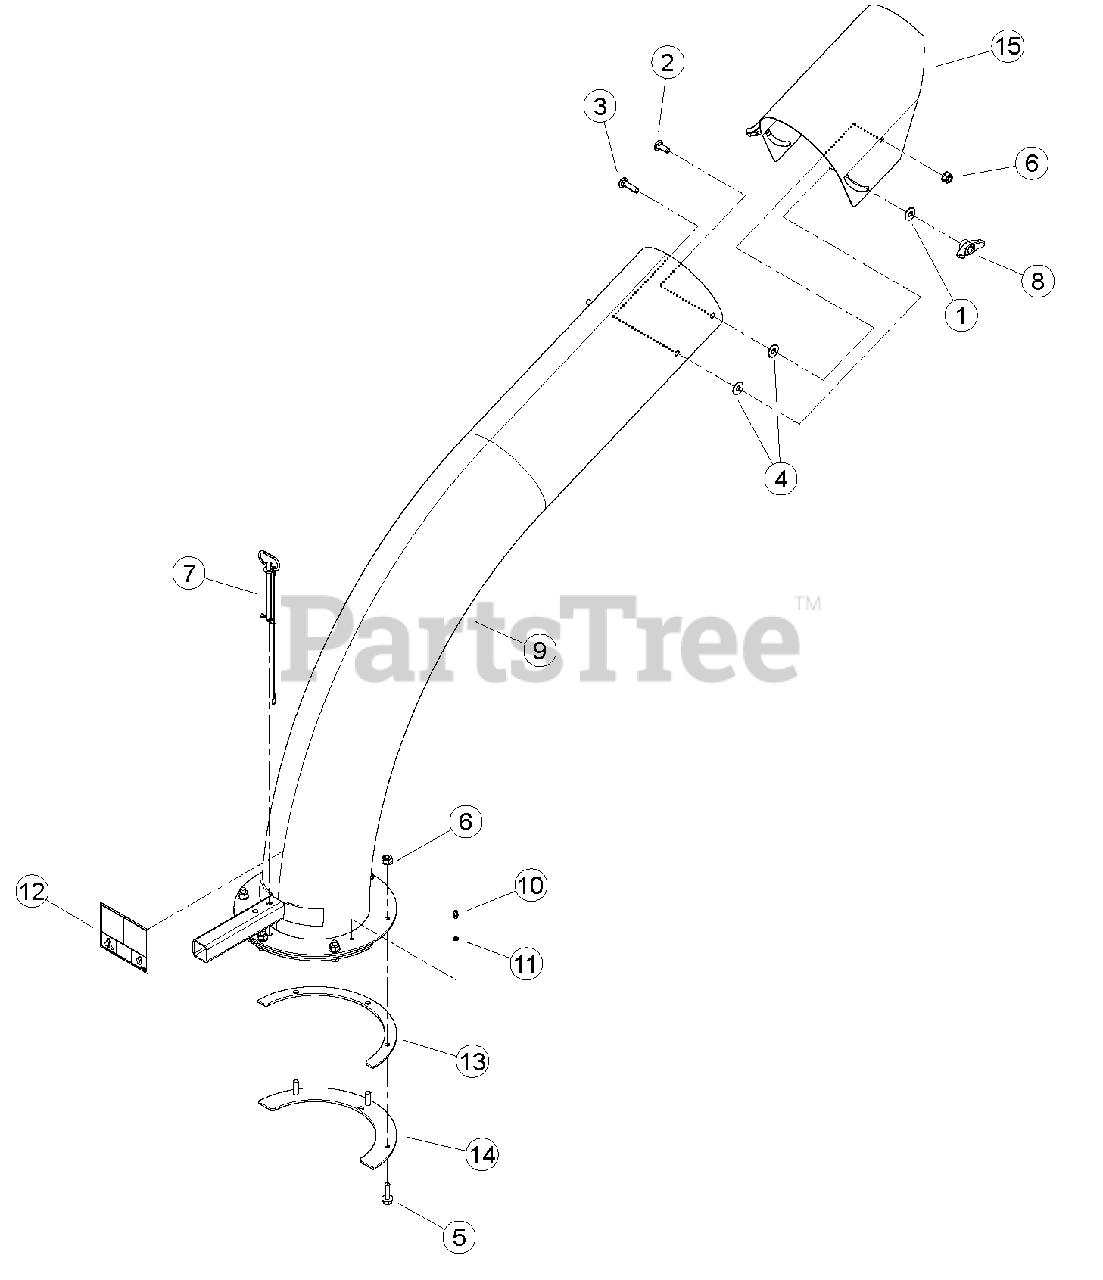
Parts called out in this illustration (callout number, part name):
1	WASHER, 3/8" FLAT ZP
2	BOLT, 3/8 X 1" GR5 CRG NC ZP
3	BOLT, 3/8 X 1-1/2" GR5 CRG NC ZP
4	WASHER, 1/2 SAE FLAT
5	BOLT, 3/8 X 1-1/4 FLANGE NC
6	NUT, 3/8-16 NYLOCK FLANGE
7	PIN, 3/8 X 4.25" DISCHARGE
8	KNOB, 3/8-16 UNC FEMALE TEE
9	ASSEMBLY, 8 INCH DISCHARGE CHUTE
10	FITTING, 1/4 SELF-TAP GREASE
11	WASHER, FLAT .254 X .400 X .048
12	DECAL, DISCHARGE DEBRIS & LOCK
13	RING, DISCHARGE SPACER
14	RING, DISCHARGE CLAMP
15	CAP, 8 INCH DISCHARGE CHUTE
